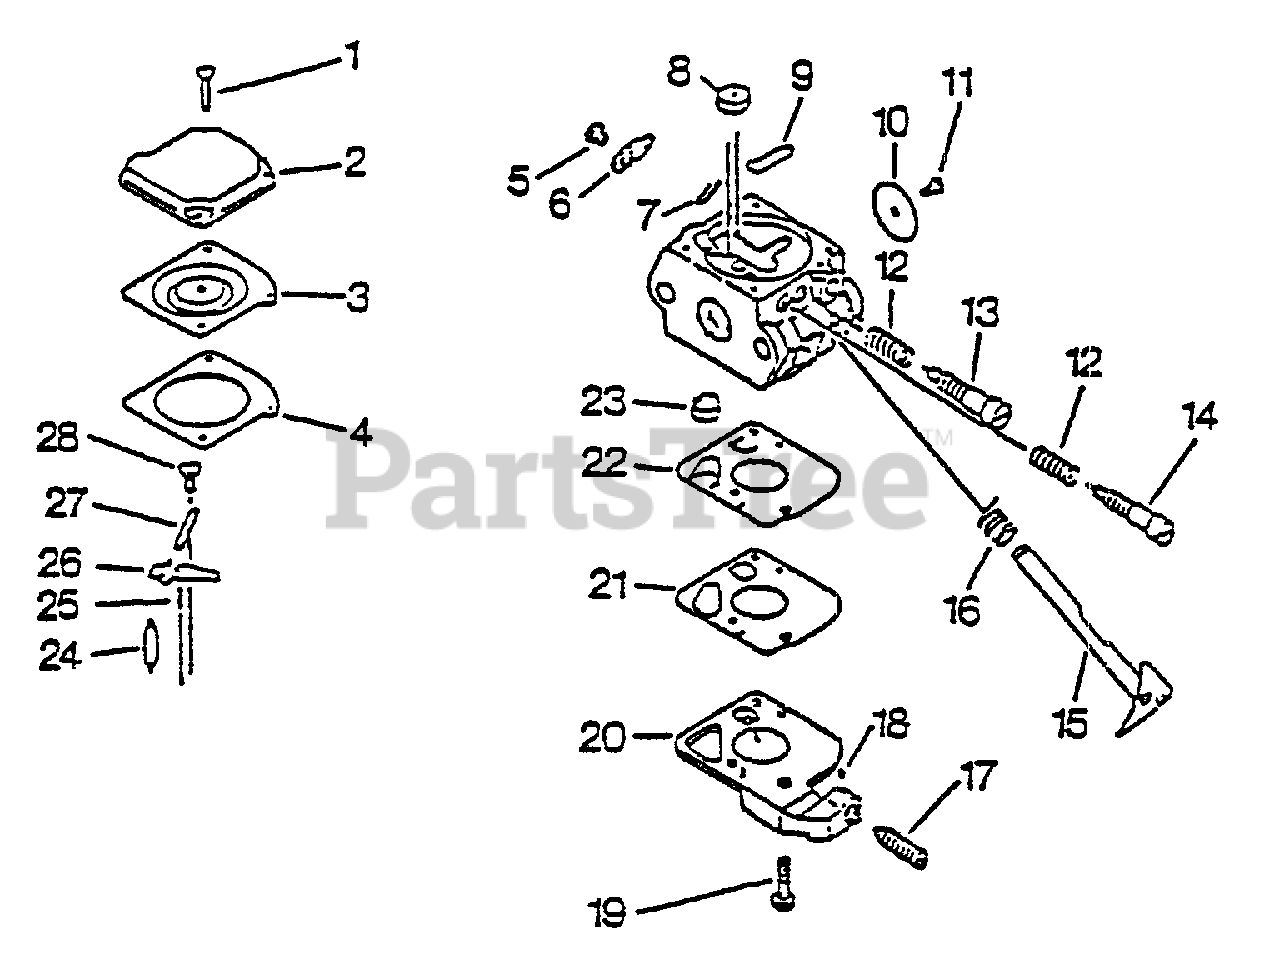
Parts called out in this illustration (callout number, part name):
2	COVER, METERING
3	DIAPHRAGM
4	GASKET, METERING
6	LEVER, THROTTLE
7	RING, RETAINING
8	NOZZLE, CHECK VALVE
9	PLUG, WELCH
10	VALVE, THROTTLE
11	SCREW
13	NEEDLE - HIGH SPEED
14	NEEDLE - LOW SPEED
15	SHAFT, THROTTLE
16	SPRING, RETURN
17	SCREW, IDLE ADJUST
18	PIECE, FRICTION
19	SCREW, PUMP COVER
20	BASE, PURGE
21	GASKET, PURGE
22	DIAPHRAGM, PURGE
23	STRAINER
24	VALVE, NEEDLE
25	SPRING
26	LEVER, METERING
27	PIN, METERING LEVER
28	SCREW, METERING LEVER PIN
